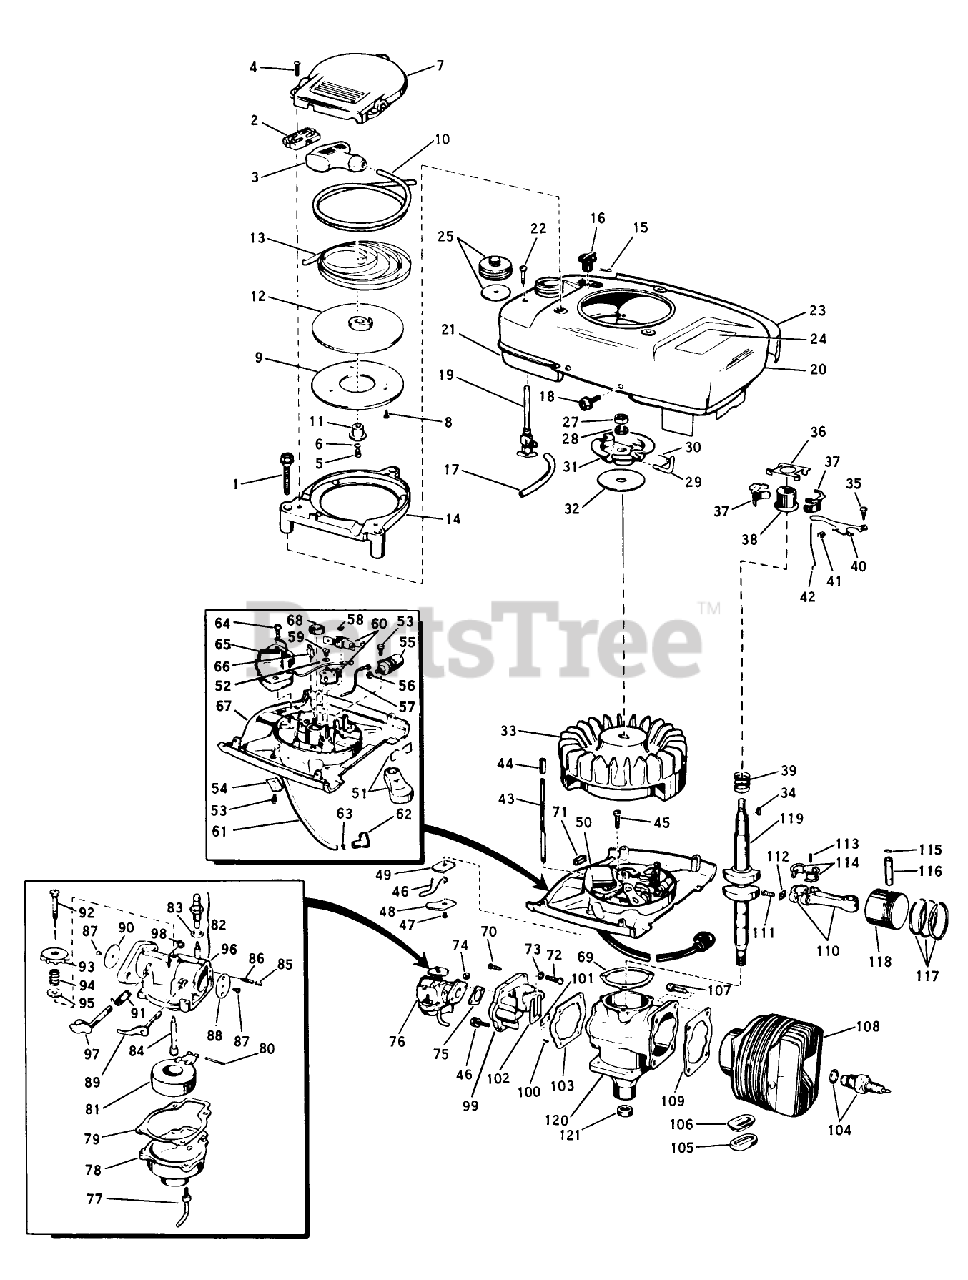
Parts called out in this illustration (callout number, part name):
9	Plate-Pulley
13	RECOIL SPRING
15	Cotter Pin-Choke Knob
16	KNOB, CHOKE BAR
18	SCREW S
19	VALVE&SCREEN SM
24	Decal-Instruction
29	PIN - STARTER
38	COLLAR S
40	GOVERNER LEVER AY
41	WEAR BLOCK S
42	GOVERNOR ROD S
46	SCREW S
47	Screw Shut-off Switch
60	BREAKER AY. S
62	Cover-Rubber
69	GASKET S
70	SCREW S
74	STOP NUT
75	GASKET S
81	Float and Arm Assembly (C-18AAR Engine)
83	WASHER
87	Screw-Choke Disc
88	Disc-Choke
89	CHOKE SHAFT&LVR AY
91	SPRING
92	NEEDLE AY. S
94	Spring-Ndl. Adj.
96	Carburetor Body (C-18AAR Engine)
101	PLATE-BACKUP, REED
104	Spark Plug
109	GASKET S
114	LINER ASM
115	RING-RETAINING
